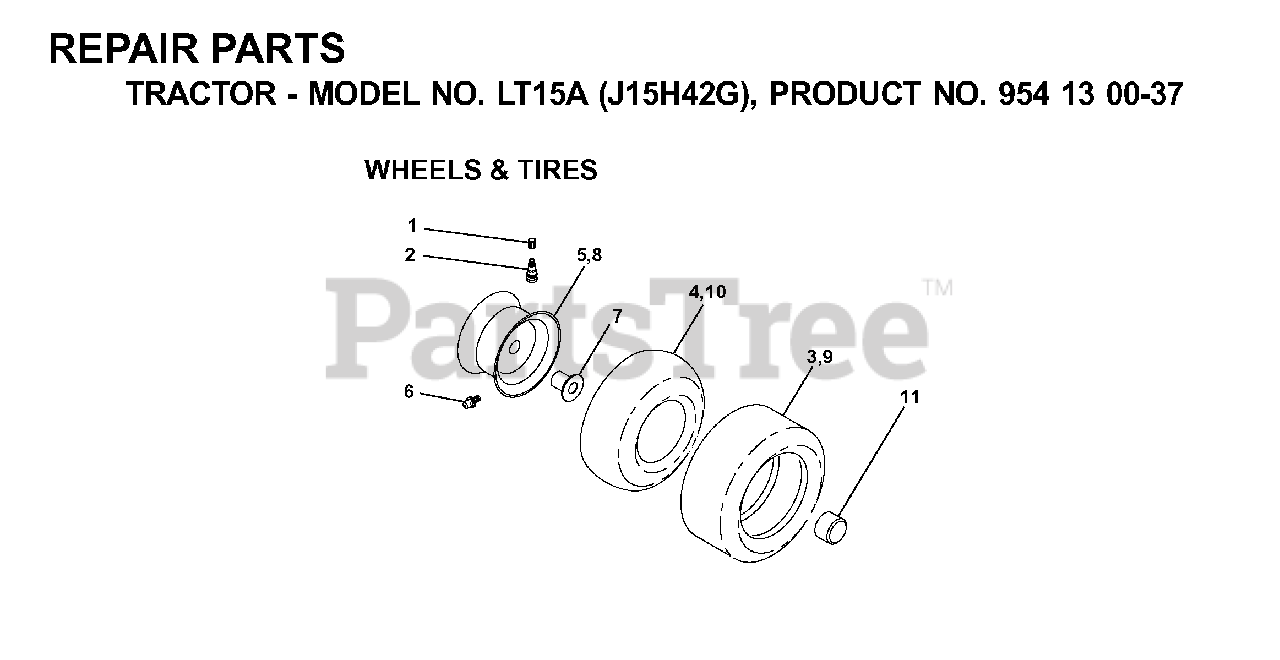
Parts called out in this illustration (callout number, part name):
1	VALVE CAP
2	VALVE STEM LT
3	TIRE HEAVY DUTY
4	TUBE.5.3/4.5/6
5	RIM ASM 6" FRONT SILVER
6	FITTING LT
7	BEARING T
8	RIM ASM 8" REAR SILVER
9	TIRE.TS.20X10-8
10	TUBE
11	CAP-HUB FRONT LT
